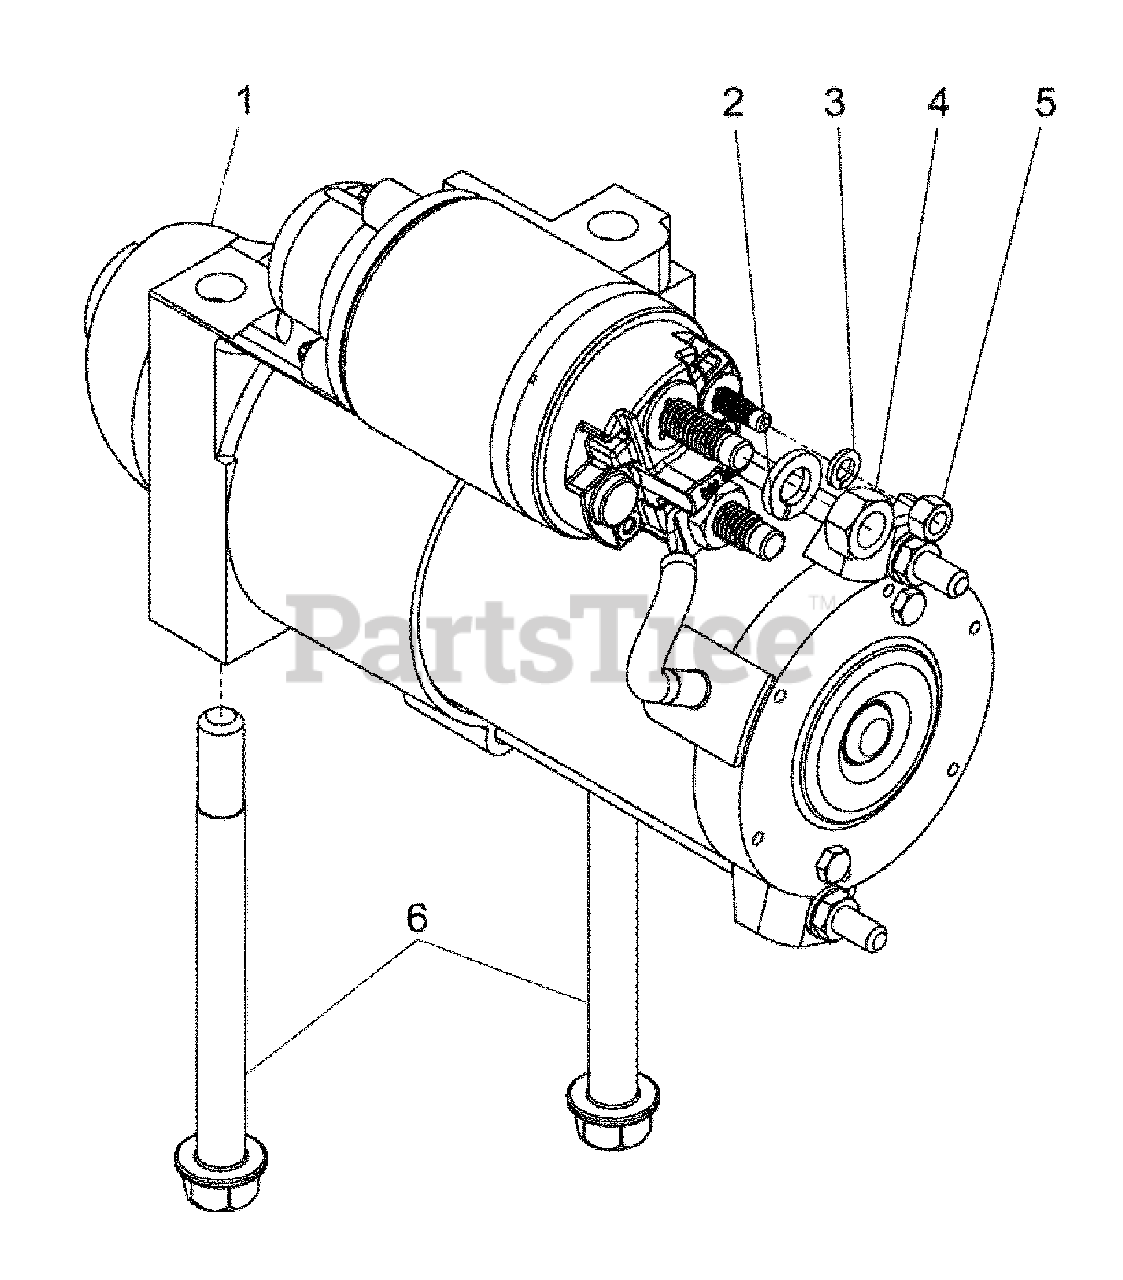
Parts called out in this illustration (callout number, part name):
2	WASHER
3	WASHER
4	NUT
5	NUT
6	BOLT
